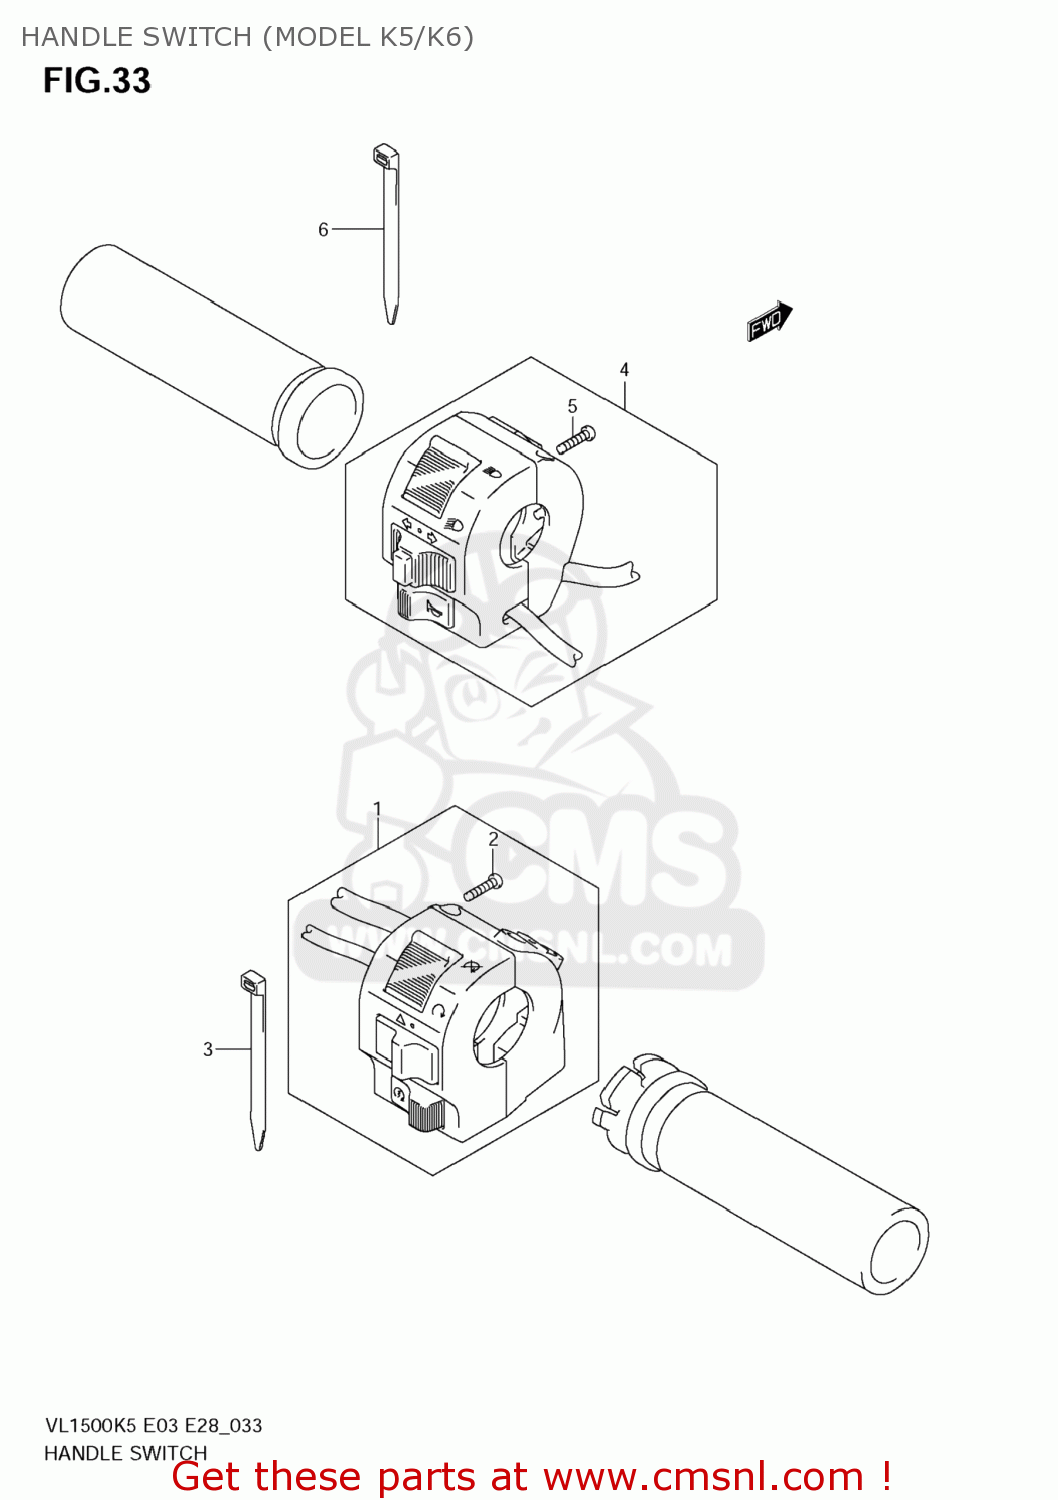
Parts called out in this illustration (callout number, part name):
1	SWITCH ASSY,HANDLE,R
2	SCREW
3	CLAMP(L:145)
4	SWITCH ASSY,HANDLE,L
5	SCREW
6	CLAMP(L:145)
